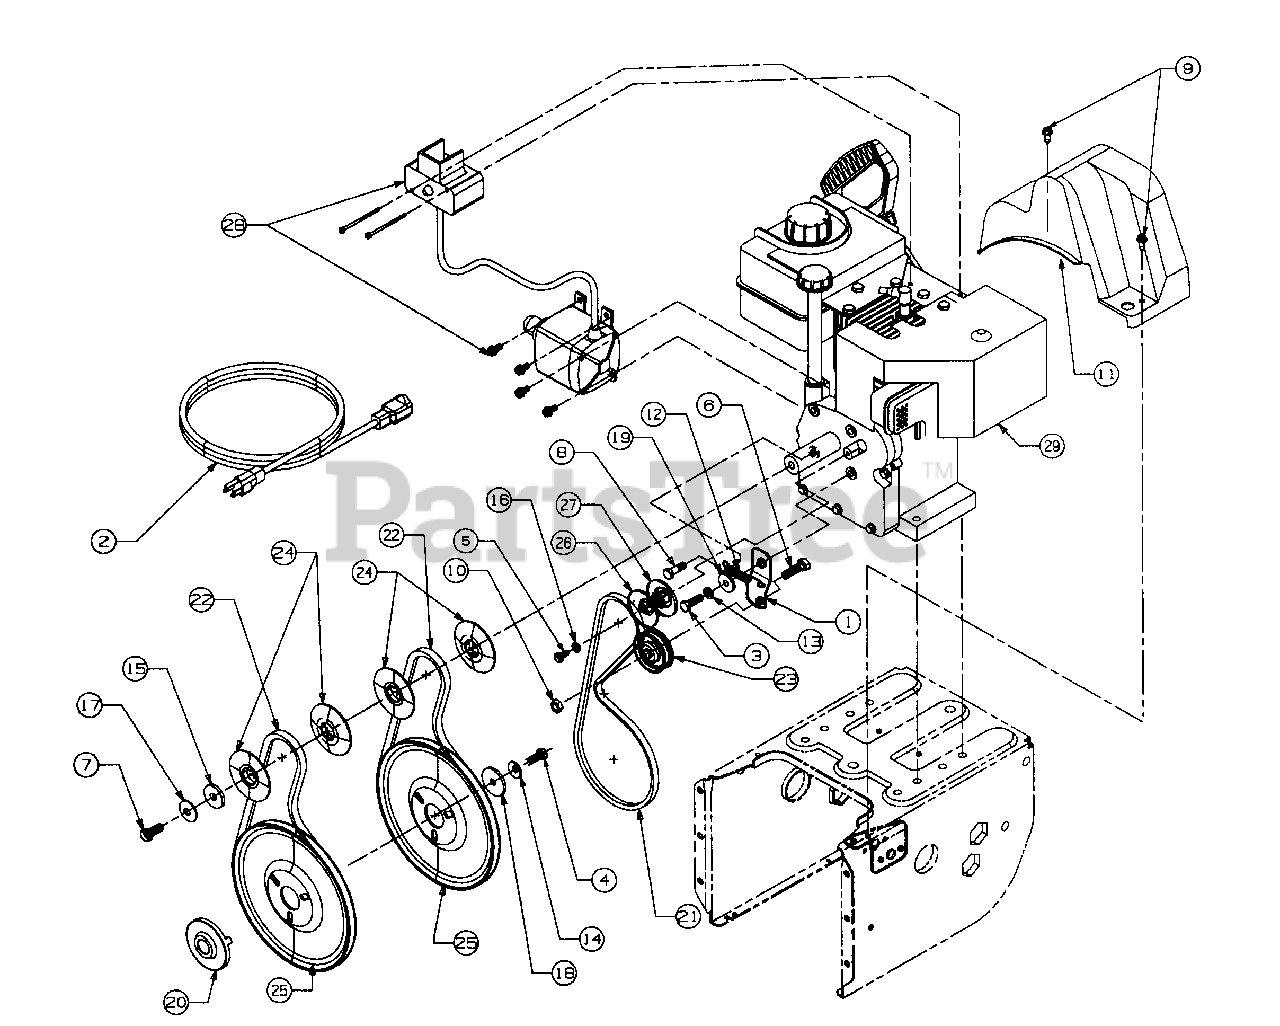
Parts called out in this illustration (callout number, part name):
3	Screw-Hex
4	Screw-Hex
5	Screw-Hex
6	Screw-Hex
7	Screw-Hex
8	Screw-Hex
9	Screw-Hex
10	Nut-Hex
11	Cover-Belt
12	Spring
13	Washer-Lock
14	Washer-Bell
15	Washer-Flat
16	Washer-Lock
17	Washer-Bell
18	Washer-Flat
19	Spacer
20	Adapter-Pulley
21	V-Belt
22	V-Belt
23	Idler-Flat
24	Pulley Half
25	Pulley-Auger
26	Pulley Half
27	Pulley Half
28	Electric Start Kit
